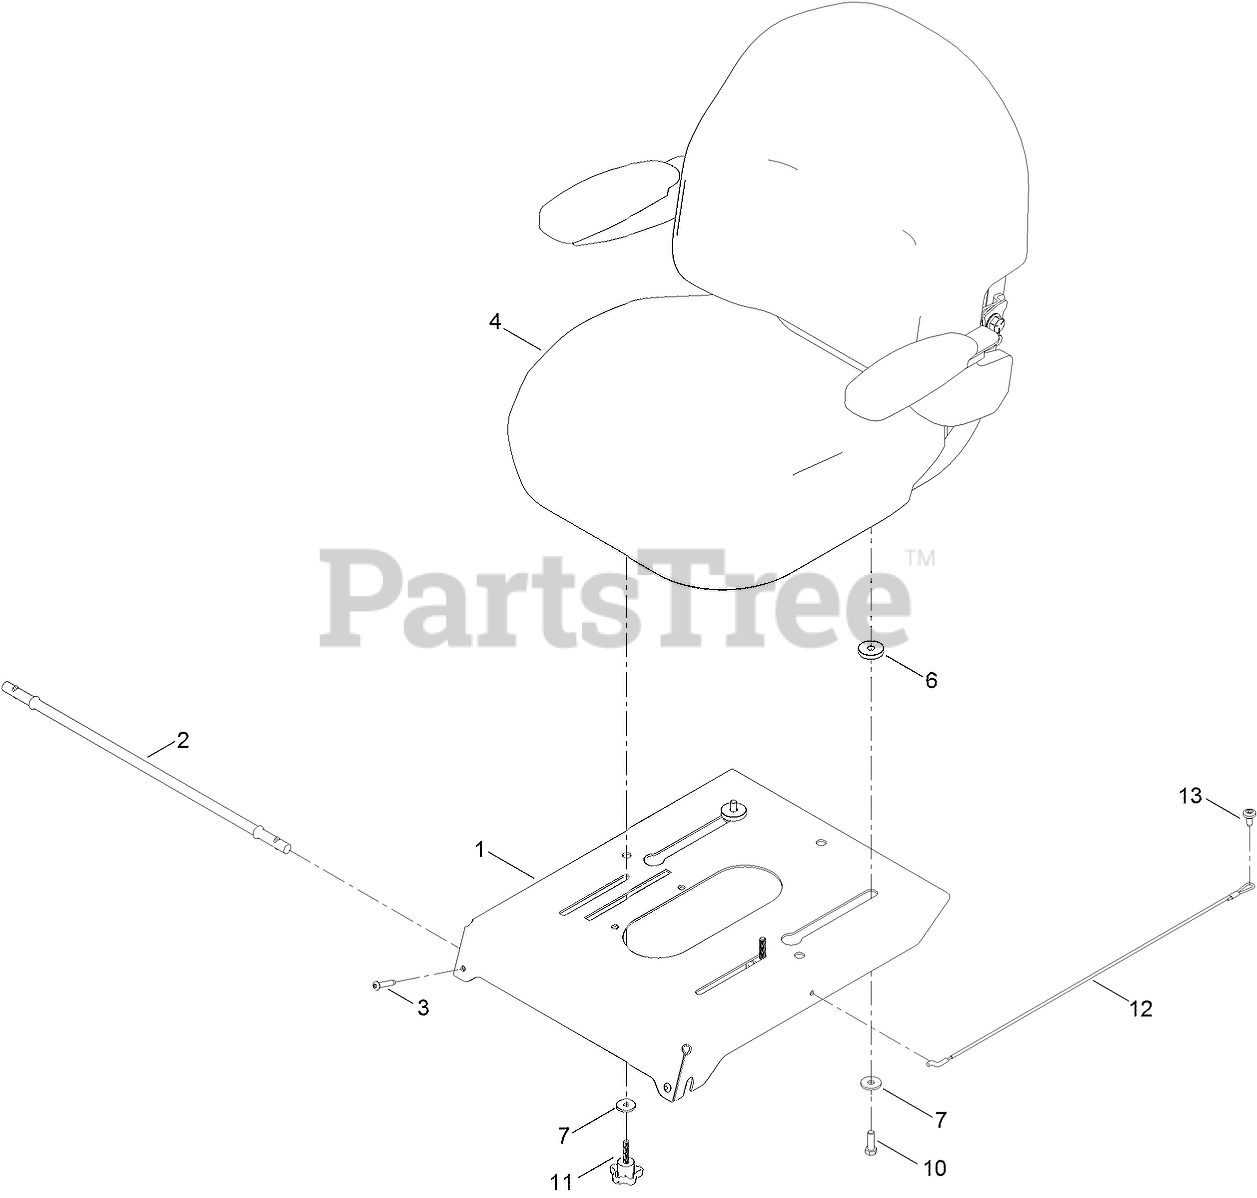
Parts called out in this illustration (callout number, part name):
1	PAN-SEAT, DELUXE
2	ROD-PIVOT
3	SCREW-TTH, THREAD ROLLING
4	SEAT ASM
6	SPACER-STEPPED
7	WASHER-FRICTION
10	SCREW-HH
12	CABLE-LANYARD
13	SCREW-SHOULDER
